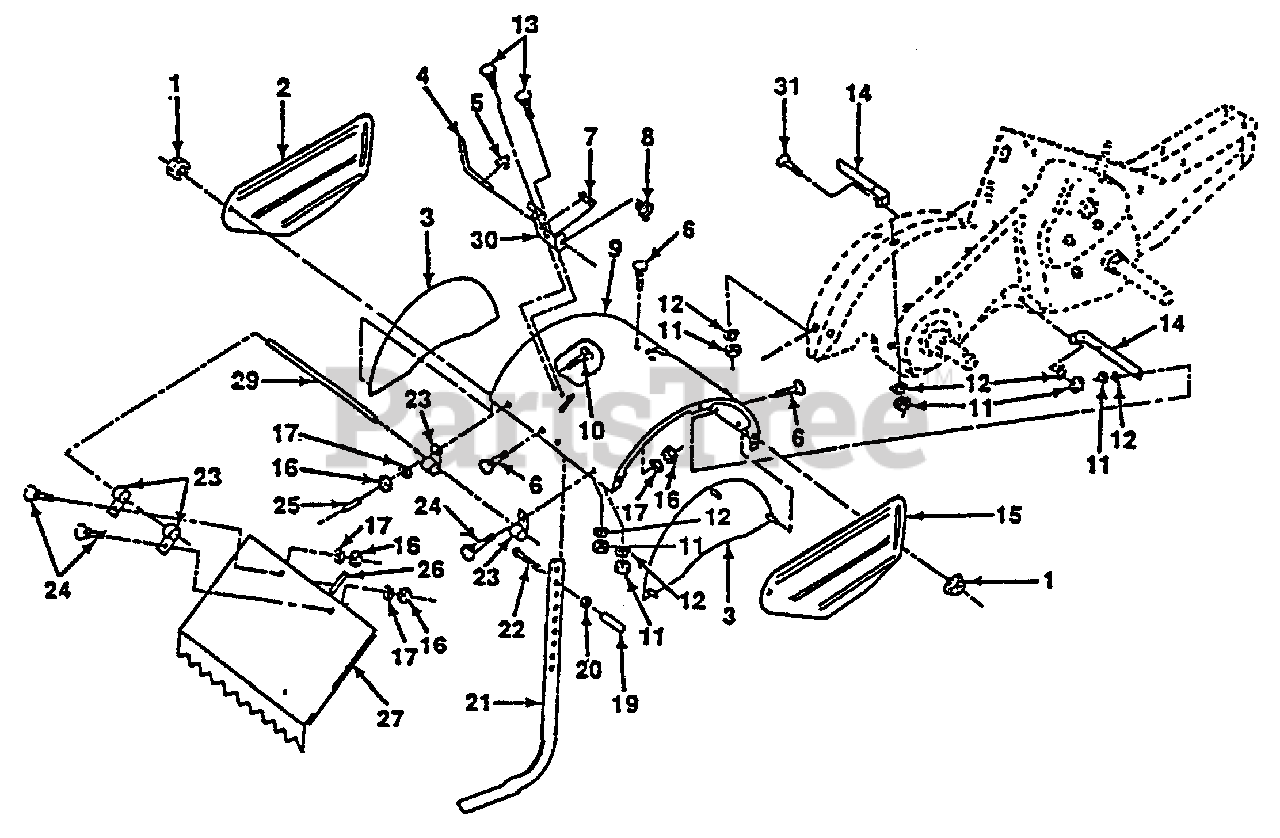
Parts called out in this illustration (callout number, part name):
1	Nut, Flange 5/16-18
2	Shield, Side outer L. H.
3	Shield, Side
4	Pin, Stake Depth
5	Ring, Klip
6	Bolt, Carriage 5/16-18 x 3/4 Gr 5
8	Spring, Depth Stake
9	Shield, Tine
10	Bolt, Carriage 1/4-20 x 1-1/4 Gr. 5
11	Nut, Hex 5/16-18
12	Washer, Lock 5/16
13	Bolt, Carriage 5/16-18 x 1
14	Bracket, Shield Tine
15	Shield, Side Outer R.H.
16	Nut, Hex 1/4-20
17	Washer, Lock 1/4
20	Nut, Hex 3/8-16
21	Stake, Depth
22	Bolt, Hex 3/8-16 x 2
24	Bolt, Carriage 1/4-20 x 1/2 Gr. 5
25	Cap, Vinyl
26	Pad, Idler
27	Shield, Leveling
29	Pin, Hinge
30	Bracket, Latch
31	Bolt, Carriage 5/16-18 x 1-1/4
